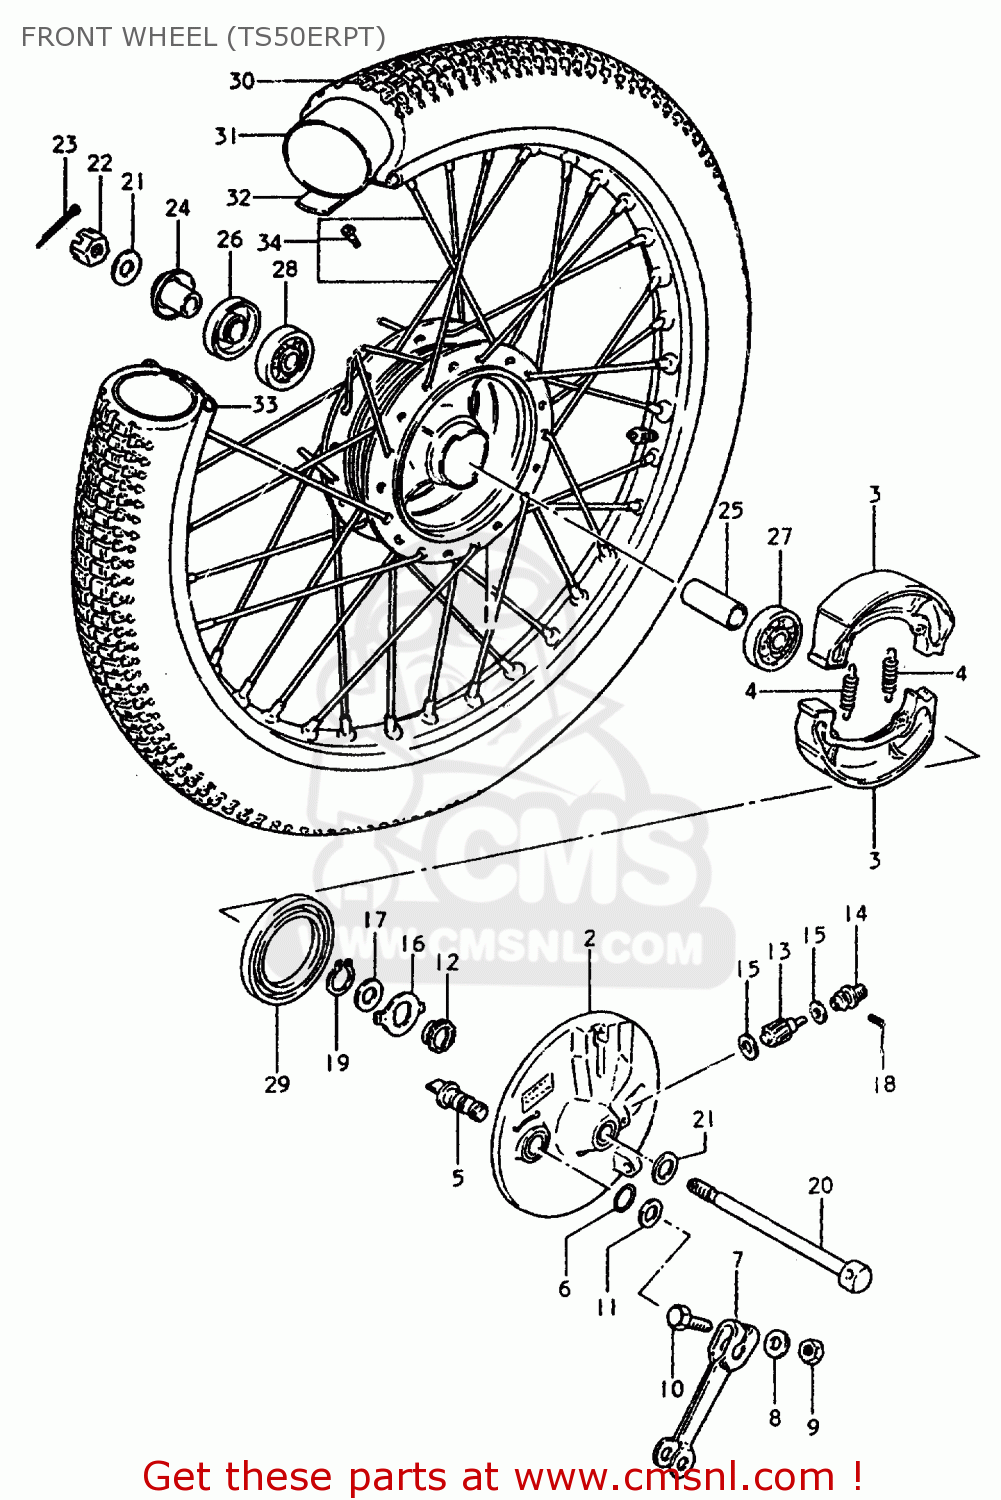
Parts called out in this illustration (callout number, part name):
1	HUB,FRONT
2	PANEL,FRONT HUB
3	SHOE,BRAKE (MCA)
4	SPRING(L:34)
5	CAM,FRONT BRAKE
6	O-RING (D:2.4 ID:13.8)
7	LEVER,FR BRAKE CAM
8	WASHER
9	NUT
10	BOLT(6X33)
11	WASHER (14.5X22X1.6)
12	GEAR, SPEEDOMETER
13	PINION,SPEEDOMETER
14	BUSH,METER GEAR OUTER
15	WASHER (5.1X9X0.4)
16	DRIVER,SPEEDOMETER GEAR
17	WASHER(16X22X1)
18	SCREW
19	CIRCLIP,15MM
20	AXLE,FRONT
21	WASHER(10.5X22X2.3)
22	NUT
23	PIN 20X20
24	SPACER,FRONT AXLE,RIGHT
25	SPACER (10.2X16X51)
26	SEAL,OIL(15X31X5)
27	BEARING
28	BEARING
29	OIL SEAL (43X58X7)
30	TIRE 2.75-19 070-483MM
31	TUBE 2.75-19 070-483MM
32	PROTECTOR,WHEEL,INNER
33	RIM,FRONT WHEEL (1.40X19)
34	SPOKE SET,FRONT
